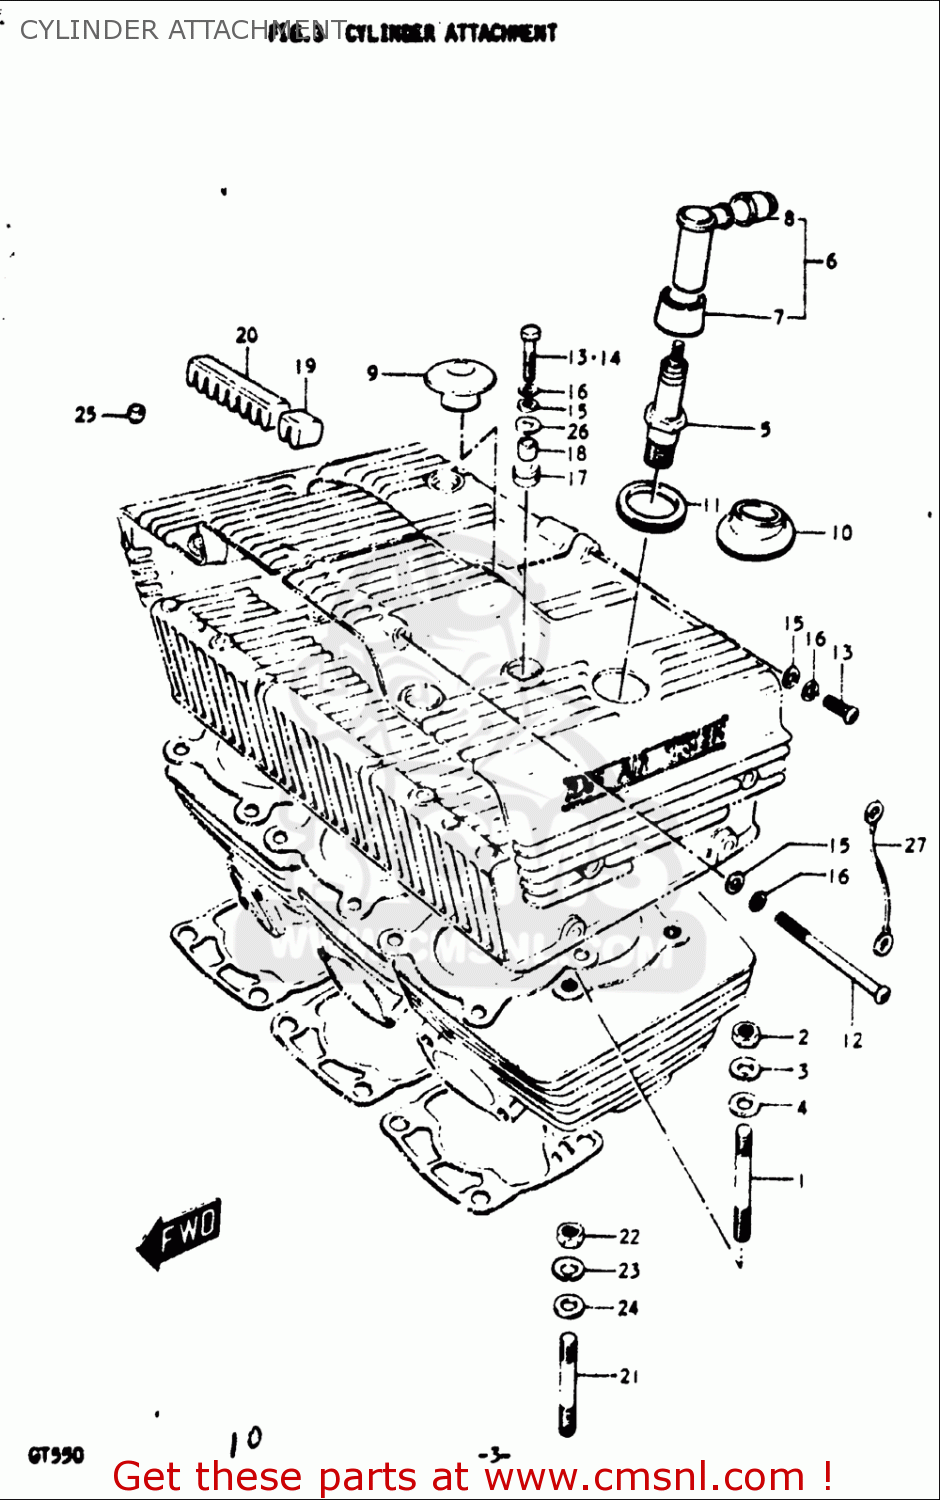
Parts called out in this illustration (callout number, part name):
1	BOLT,STUD
2	NUT
3	WASHER,LOCK
4	WASHER
5	PLUG,SPARK
6	CAP,SPARK PLUG
7	SEAL,SPARK PLUG
8	SEAL,HIGH TENSION CORD
9	RING, SPARK PLUG
10	RING, SPARK PLUG
11	RING, SPARK PLUG
12	SCREW
13	SCREW
14	BOLT
15	WASHER
16	WASHER,LOCK
17	CUSHION
18	SPACER(6.1X8X12)
21	BOLT
22	NUT
23	WASHER,LOCK
24	WASHER
26	WASHER(6.5X14X1.6)
27	LEAD WIRE
